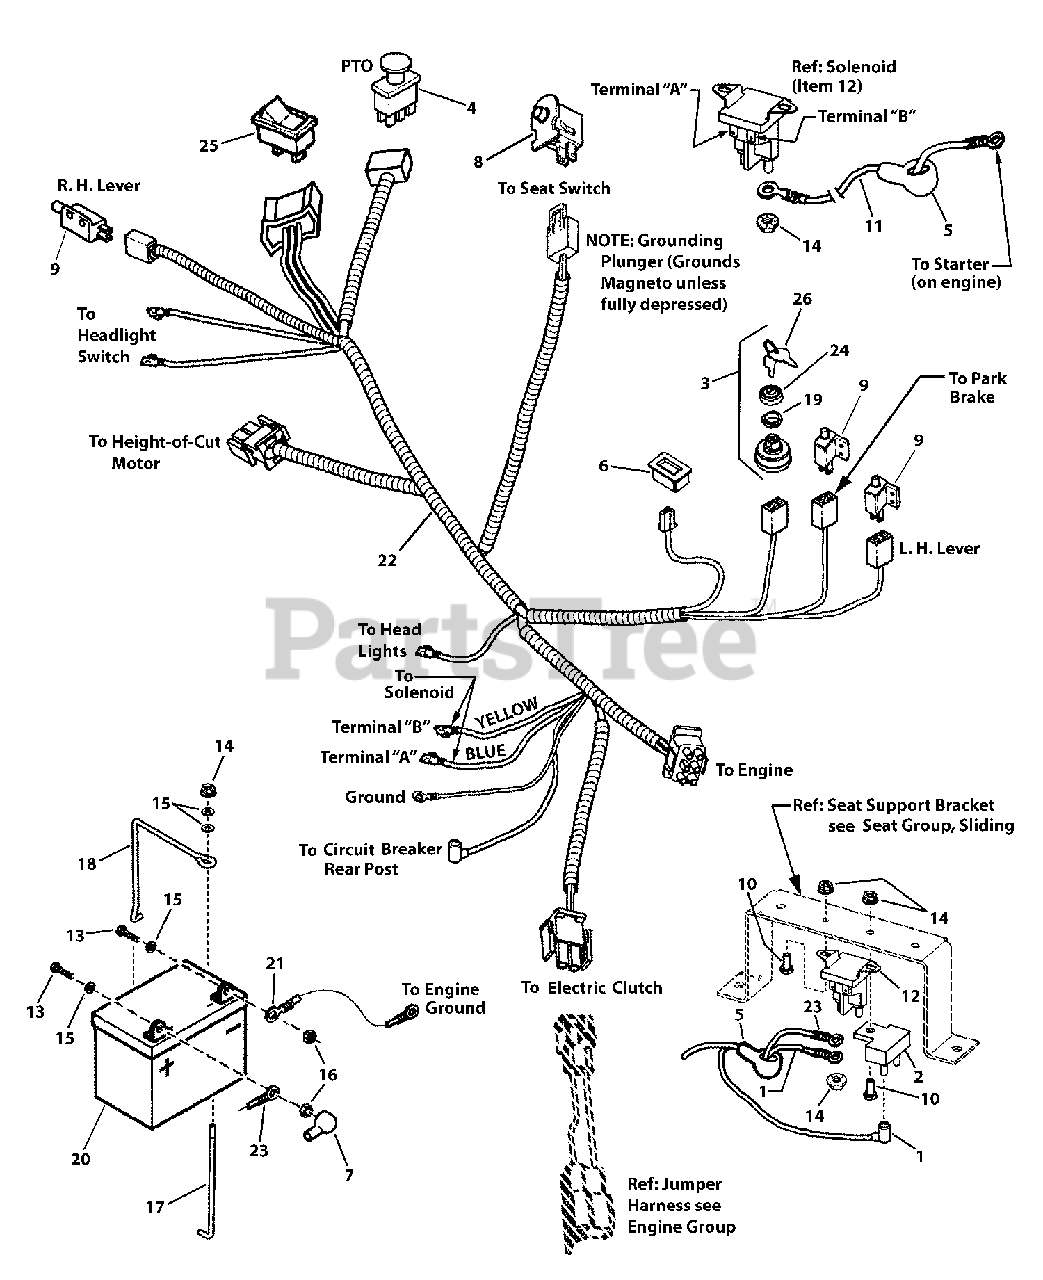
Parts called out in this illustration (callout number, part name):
1	WIRE, 12 Gage, 8", Red
2	BREAKER, Circuit 12 Volt 20 AMP w/Tab
3	SWITCH ASSEMBLY, Ignition, .625-32 6 Pin Indak
4	SWITCH, PTO, Push/Pull Symbols
5	COVER, Terminal, Red Vinyl
6	HOUR METER, Digital, No Alarms
7	BOOT, Insulator, Battery Terminal, PVC, Red
8	SWITCH, Push Button (NC) (gray)
9	SWITCH, DPDT (NC/NO) (Gray)
10	SCREW, 1/4-20 x 5/8" Hex Head Cap, GR 5
11	CABLE, Starter, 8 Gage, 14, Black
12	SOLENOID, Super Trombetta - 2 Terminal
13	SCREW, 1/4-20 x 5/8" Hex Head Cap, GR 5 or B
14	NUT, 1/4-20 Hex Flange Lock, YZ
15	WASHER, 1/4" Flat
16	NUT, 1/4-20 Hex Center Lock, GR B
17	HOLD DOWN, Battery
18	BRACKET, Battery
19	NUT, 5/8"-32 E-Start
20	BATTERY, 12 Volt, 230 CCA
21	CABLE, Battery Negative, 8 Gage, 20", Black
22	HARNESS, Wiring, ZT
23	CABLE, Battery Positive, 8 Gage, 18, Red
24	CAP, Ignition Switch
25	SWITCH, Rocker Electric Height-Of-Cut
26	KEYS, Blister Pk (KIDS+MWRS DON'T MIX) English/Spanish (set of two, one coated)
